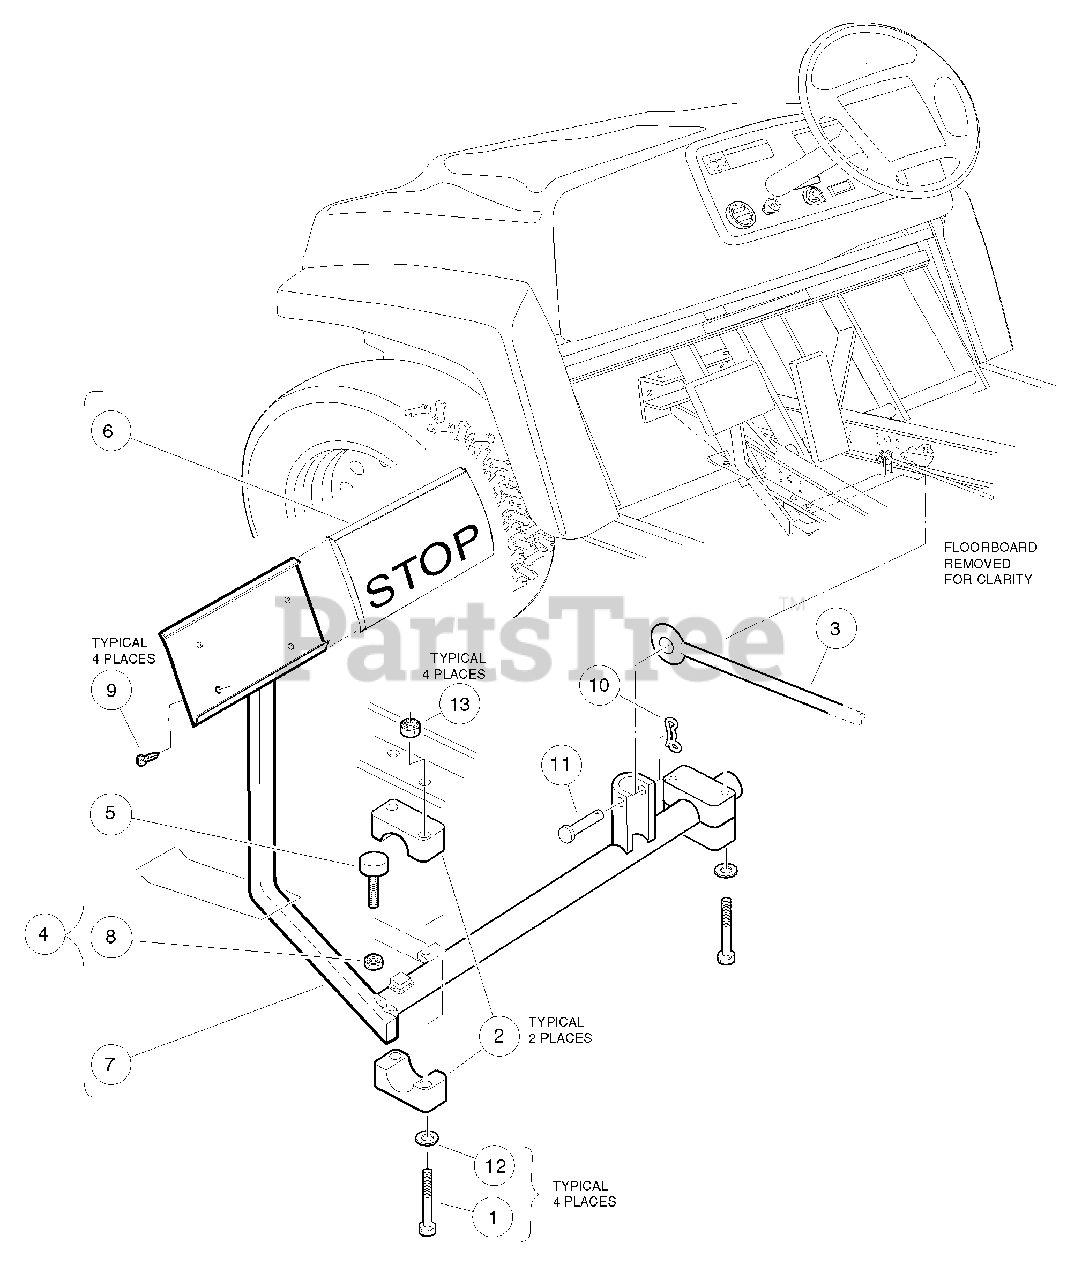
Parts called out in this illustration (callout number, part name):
1	Screw, 5/16-18 X 2.50 Hex Cap
2	Package, Brake Mounting Block
3	Rod, Equalizer, 13.30"
4	Assembly, Brake Pedal
5	Bumper, Rubber
6	Pad, Hydraulic Brake Pedal
7	Brake Pedal Weld Asm
8	Nut, 1/4-20 Hex
9	Screw, #10-16 Type AB, Sheet Metal
10	Pin, Bow Tie Locking - .072
11	Pin, 3/8 X 1-5/16 Clevis
12	Washer, 5/16 Type A Flat
13	Locknut, 5/16-18 Nylon Insert
